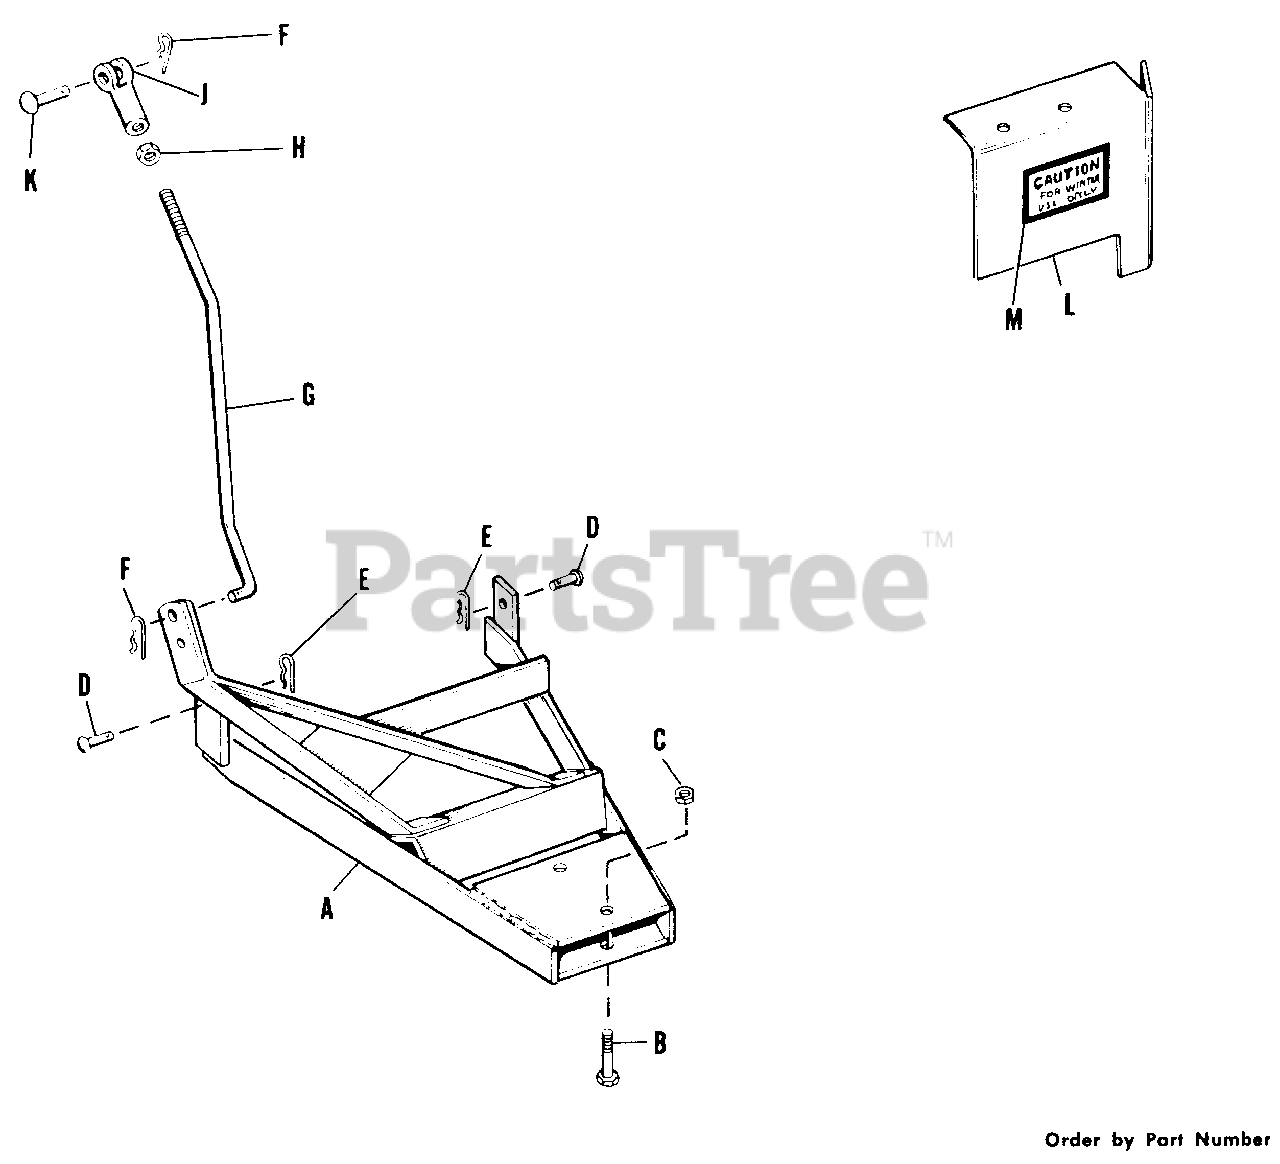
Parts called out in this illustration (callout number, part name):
A	Bar Assembly, Push
B	Capscrew, Hex Hd., 1/2"-13 N.C. x 2-1/2" lg.
C	Nut, Hex, Full. Lock, 1/2"-13 N.C.
D	Pin
E	Clip, Spring
F	Clip, Spring
G	Rod, Front Lift
H	Nut, Full, Hex, 1/4"-20 N.F.
J	Yoke End, Adjusting
K	Pin, Yoke
L	Deflector, Hot Air
M	Decal, "Caution"
